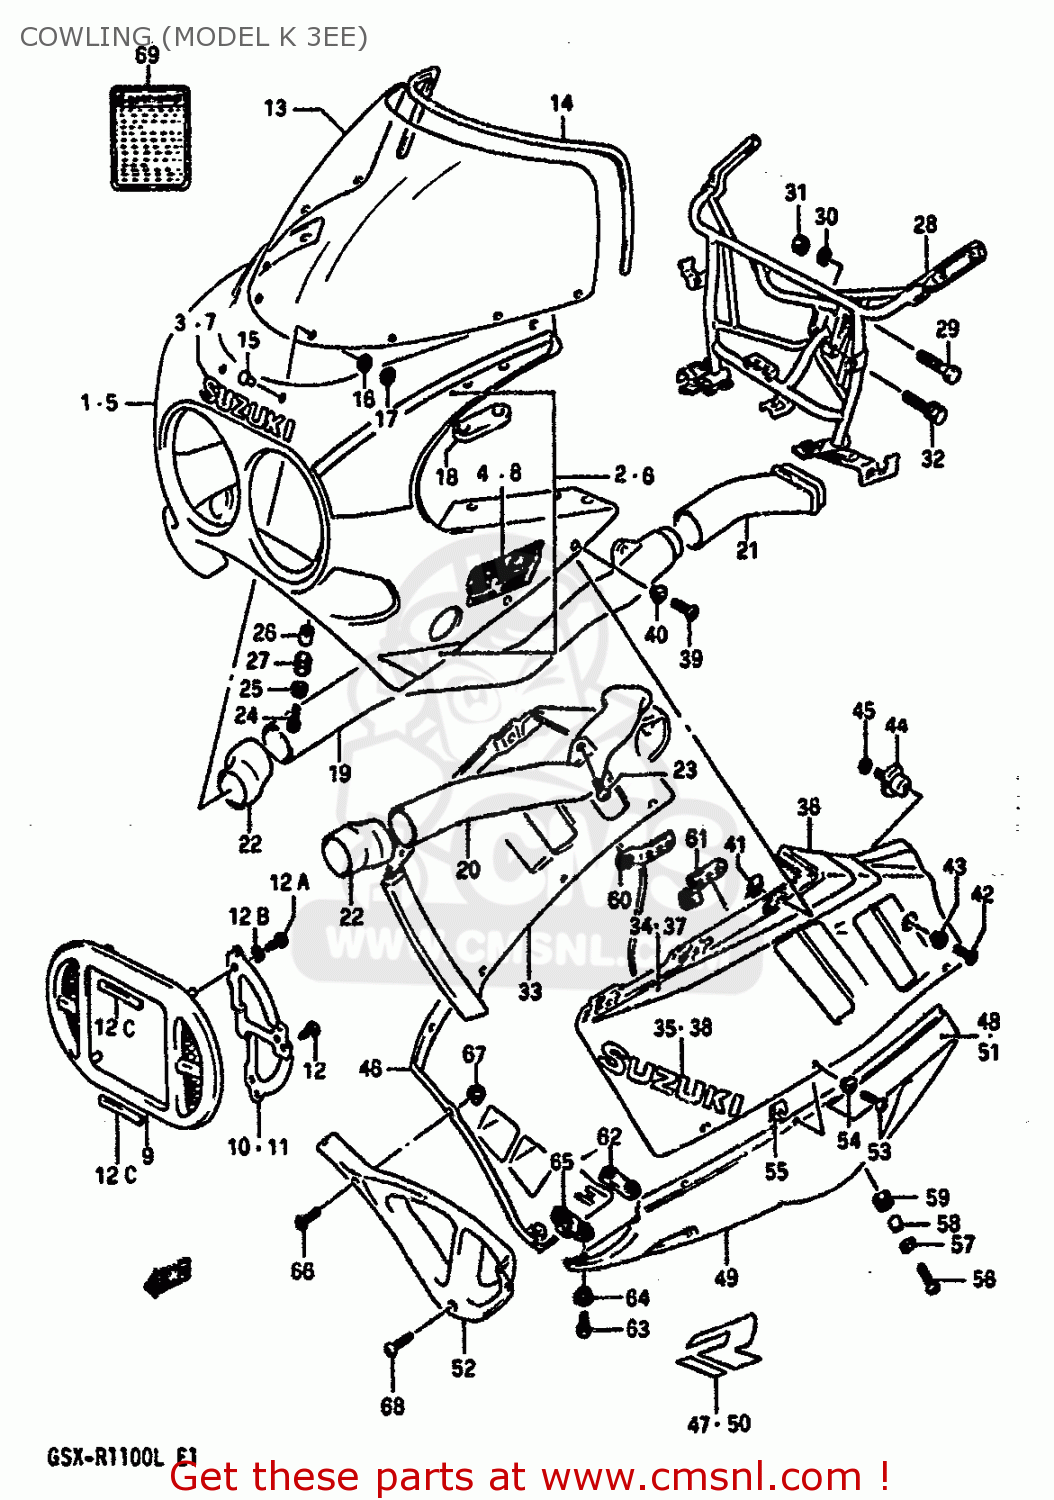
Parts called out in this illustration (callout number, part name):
1	BODY ASSY,COWLING (BLACK)
2	TAPE SET
3	EMBLEM,COWLING FR
4	EMBLEM
5	BODY ASSY,COWLING (BLACK)
6	TAPE SET
7	EMBLEM,COWLING FR
8	EMBLEM
9	COVER,FRONT (BLACK)
10	PLATE,COVER RH
11	PLATE,COVER LH
12	TAPPING SCREW 4X10/A
12A	SCREW
12B	SPACER
12C	CUSHION
13	SCREEN SET,WIND
14	MOLDING
15	PIN,WINDSCREEN
16	CUSHION
17	NUT
18	CUSHION,RR VIEW MIRRORR
19	PIPE,AIR INTAKE FR,R
20	PIPE,AIR INTAKE,FRONT
21	PIPE,AIR INTAKE RR,R
22	JOINT,AIR INTAKE
23	SCREW
24	SCREW(6X20)
25	WASHER(6.5X18X1)
26	SPACER
27	CUSHION
28	BRACE,COWLING
29	BOLT
30	WASHER,LOCK,8.
31	NUT ,8MM
32	BOLT
33	COVER,SIDE RH (BLACK/RED)
34	TAPE SET,RH
35	EMBLEM,COWLING SIDE
36	COVER,SIDE LH (BLACK/RED)
37	TAPE SET,LH
38	EMBLEM,COWLING SIDE
39	SCREW(5X18)
40	WASHER(5.2X14X1.5)
41	NUT,HEADLAMP HOUSING,UPPER
42	SCREW(6X12)
43	WASHER(6.3X16X1.5)
44	CUSHION,COWLING
45	WASHER,LOCK
46	COWLING,UNDER RH (BLACK/RED)
47	EMBLEM
48	TAPE,RH
49	COWLING,UNDER LH (BLACK/RED)
50	EMBLEM
51	TAPE,LH
52	COWLING,UNDER,CENTER
53	SCREW(5X18)
54	WASHER(5.2X14X1.5)
55	NUT,HEADLAMP HOUSING,UPPER
56	SCREW(6X20)
57	WASHER(6.5X18X1)
58	SPACER
59	CUSHION
60	BRACKET
61	BRACE,COWLING UNDER,LH
62	BRACE,COWLING LWR COVER RR
63	SCREW(6X16)
64	WASHER(6.3X16X1.5)
65	BRACE,COWLING LWR COVER
66	SCREW(5X14)
67	NUT
68	SCREW(6X16)
69	LABEL (WARNING)
